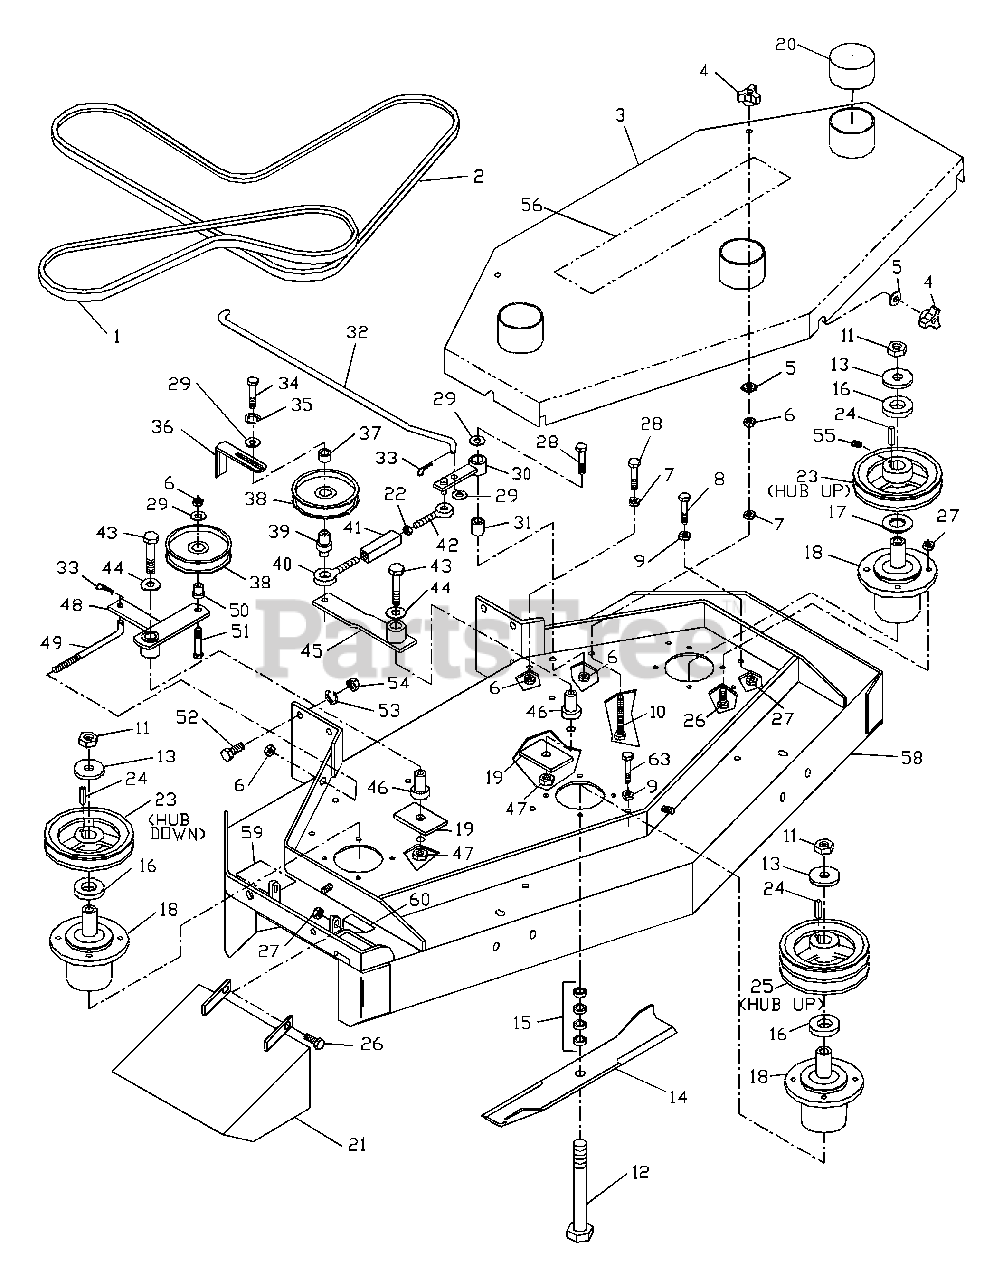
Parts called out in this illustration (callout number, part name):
1	AUX. BLADE BELT
2	BLADE BELT 48
3	48" BELT SHIELD
4	THREE PRONG KNOB
5	3/8 SEALING WASHER
8	HCS 5/16CX3
9	HFLN 5/16C
10	TAP BOLT - 3/8C X 4 1/2
12	HCS 5/8F X 8 1/2
12	HCS 5/8F X 9 (CENTER)
13	SUPPORT WASHER
14	BLADE 16 1/4"
15	BLADE SPACERS
17	MACH. BUSHING 10 GA.
18	HOUSING ASM.
21	DEFLECTOR CHUTE
22	5/16C HEX NUT
23	PULLEY W/SET SCRS
24	1/4SQ. KEY X 1 1/8
25	DOUBLE PULLEY
26	HCS 5/16C X 1
28	HCS 3/8C X 2 1/4
29	FW 3/8 STD
30	ENGAGEMENT ARM
31	SLEEVE BUSHING
32	BLADE ROD 48"
33	#2 HAIR PIN
34	HCS 3/8C X 2 1/2
35	3/8 LOCK WASHER
38	IDLER PULLEY
39	EYE BOLT PIVOT
40	LEFT HAND EYE BOLT
41	TURNBUCKLE
42	RH. EYE BOLT
43	HCS 1/2C X 2 3/4
44	1/2 FLAT WASHER
46	IDLER SPINDLE
47	1/2C NYLOC NUT
48	AUX. IDLER ARM
49	TENSION ROD
50	IDLER FLANGE BUSHING
51	HCS 3/8C X 1 3/4
52	HCS 7/16C X 1 1/2
53	7/16 LOCK WASHER
54	7/16C HEX NUT
55	5/16 NYLOC SET SCREW
56	DECAL, HUSQVARNA
57	DECAL, NASCAR
58	48" DECK W/DECALS
59	DECAL, SEVERING
60	DECAL, CPSC
63	HCS 5/16C X 4
